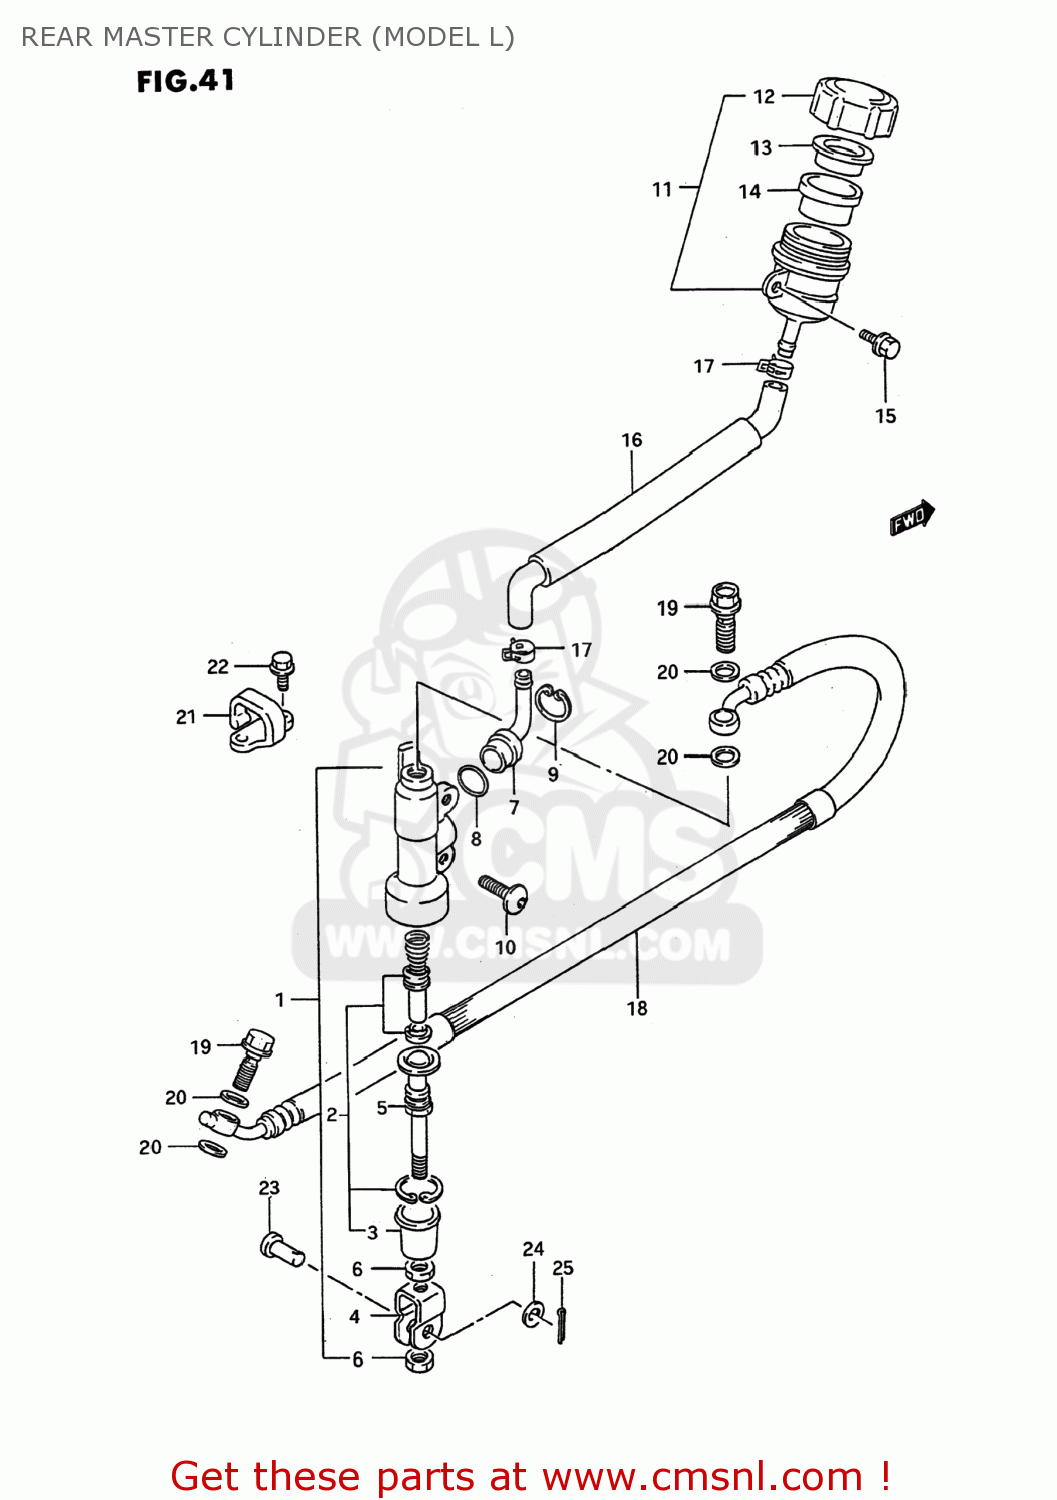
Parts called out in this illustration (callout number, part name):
1	CYLINDER ASSY,RR MASTER
2	PISTON/CUP SET
3	BOOT
4	YOKE
5	ROD,PUSH
6	NUT
7	CONNECTOR
8	O RING
9	CIRCLIP
10	SCREW(6X16)
11	TANK ASSY,RESERVOIR
12	CAP
13	PLATE
14	DIAPHRAGM
15	BOLT
16	HOSE,RESERVOIR TANK
17	CLAMP,RESERVOIR HOSE
18	HOSE,REAR BRAKE
19	BOLT UNION
20	WASHER(10X15X1.5)
21	GUIDE,RR BRAKE HOSE
22	SCREW(5X10)
23	PIN(8X20)
24	WASHER(8.5X13X1.6)
25	PIN
